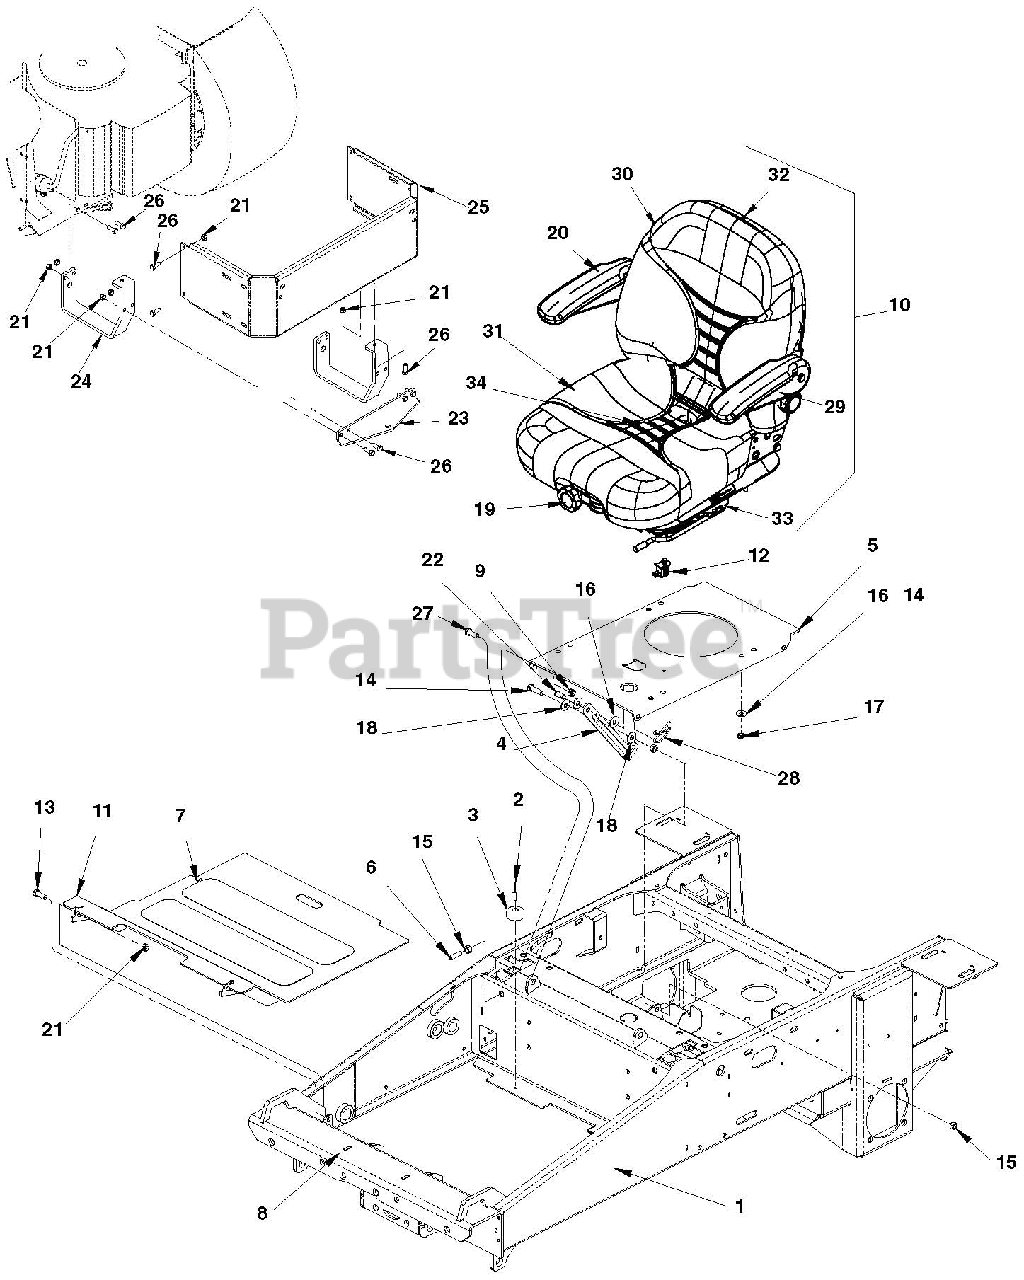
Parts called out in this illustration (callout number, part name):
1	FRAME WITH DECALS ACM
2	RIVET, 3/16 X .500 POP ST
3	BUMPER, RUBBER .625 X 1.50 DIA
4	BAR, SEAT LOCK
5	PLATE, SEAT
6	SET SCREW, 3/8-16X1.25 SK CUP
7	TAPE, NON-SLIP - 4.00 X 18.00
8	TAPE, NON-SLIP - 2.50 X 21.50
9	LOCKNUT, 3/8-16 CROWN Y
10	SEAT-SUSP-LT GRY-SEAT BLT BUSH
11	WLDT, FOOT PLATE
12	SWITCH- SNAP MTG N.O.
13	BOLT, 3/8-16X1.00 HEX 5 Y
14	BOLT, 3/8-16X1.25 HEX 5 Y
15	NUT, 3/8-16 STD HEX GR5 Y
16	WASHER, .313 REG FLAT Y
17	LOCKNUT, 5/16-18 CROWN Y
18	WASHER, .375 REG FLAT Y
19	KIT-SEAT KNOB
20	KIT-RH ARMREST ASSEMBLY REPLAC
21	LOCKNUT, 3/8-16 CROWN Y
22	PIN, CVS .375X.750X.516 Y
23	PLATE, HITCH
24	ARM, HITCH SUPPORT
25	PLATE, REAR BUMPER
26	BOLT, 3/8-16X1.00 HEX 5 Y
27	BOLT, 1/2X1.06X3/8-16 SLD 5 Y
28	RING, RUE .375 X .054 X 1.254
29	KIT-LH ARMREST ASSEMBLY REPLAC
30	KIT-BACK CUSHION-LIGHT GRAY
31	KIT-SEAT CUSHION-LIGHT GRAY
32	KIT-SEAT BACK PANEL
33	KIT-SEAT SLIDE
34	KIT-SPRING AND SADDLE
